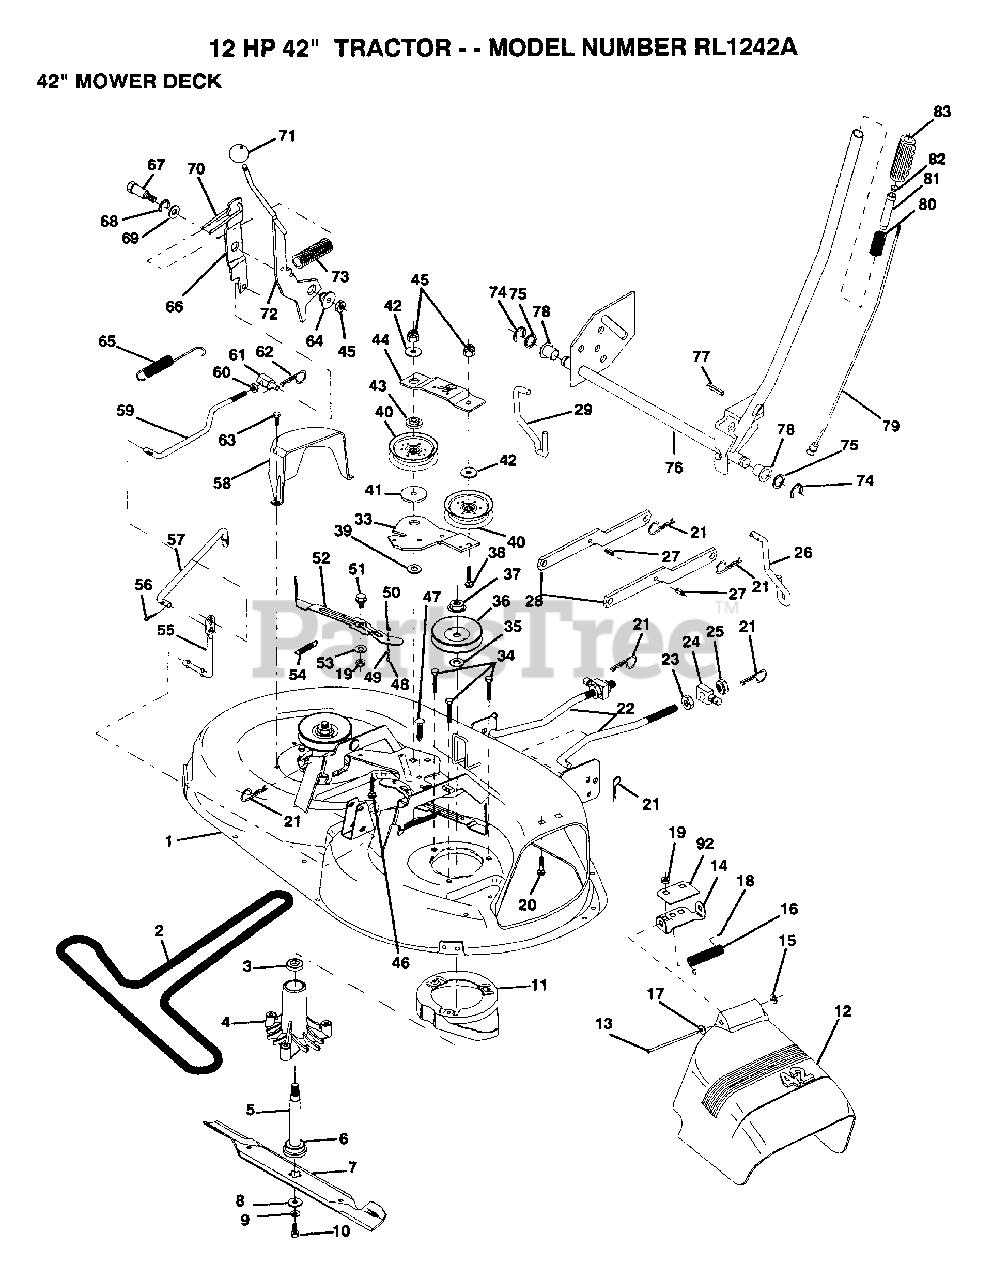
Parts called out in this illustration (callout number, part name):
2	BELT-V.92.4.MWR
3	BEARING
4	HSG ASM MANDREL
6	BEARING.BALL
8	WASHER BLADE
10	BLADE BOLT
12	DEFLECTOR.SHIELD
13	HINGE ROD
14	DEFLECTOR BRKT
15	NUT PUSH M
16	SPRING TORSION
17	WASHER
18	CAP-SLEEVE LT
20	BOLT
22	LINK.FRONT
23	NUT
24	TRUNION
25	NUT.LK.W/WSH.1/2.
26	LIFT LINK RH
27	"PIN,SPRING"
29	LINK LIFT LH
33	IDLER ARM
35	WASHER
38	BOLT
39	HARDENED WASHER
40	FLAT IDLER PULLEY
41	SPACER RETAINER
42	WASHER GT
43	RETAINER SPACER
44	IDLER ARM STIFF
46	BOLT CARRIAGE
47	XMAS TREE FASTNER
48	SHOULDER BOLT
50	LOCKNUT
52	BRAKE PAD ARM ASM
53	HARD SMALL WASHER
54	SPRING EXTENSION
55	PIVOT ROD
57	CLUTCH ROD SECOND
60	NUT
61	TRUNION
62	RETAINER M
63	SCREW LT
64	BUSHING
65	RETURN SPRING
66	CLUTCH ARM SECOND
67	SHOULDER BOLT
68	RING
69	WASHER
70	SPRING KEEPER
72	CLUTCH ARM PRI AS
75	WASHER
77	PIN-GROOVE LT
78	NYLON BEARING
83	GRIP
92	STIFFENER BRKT
